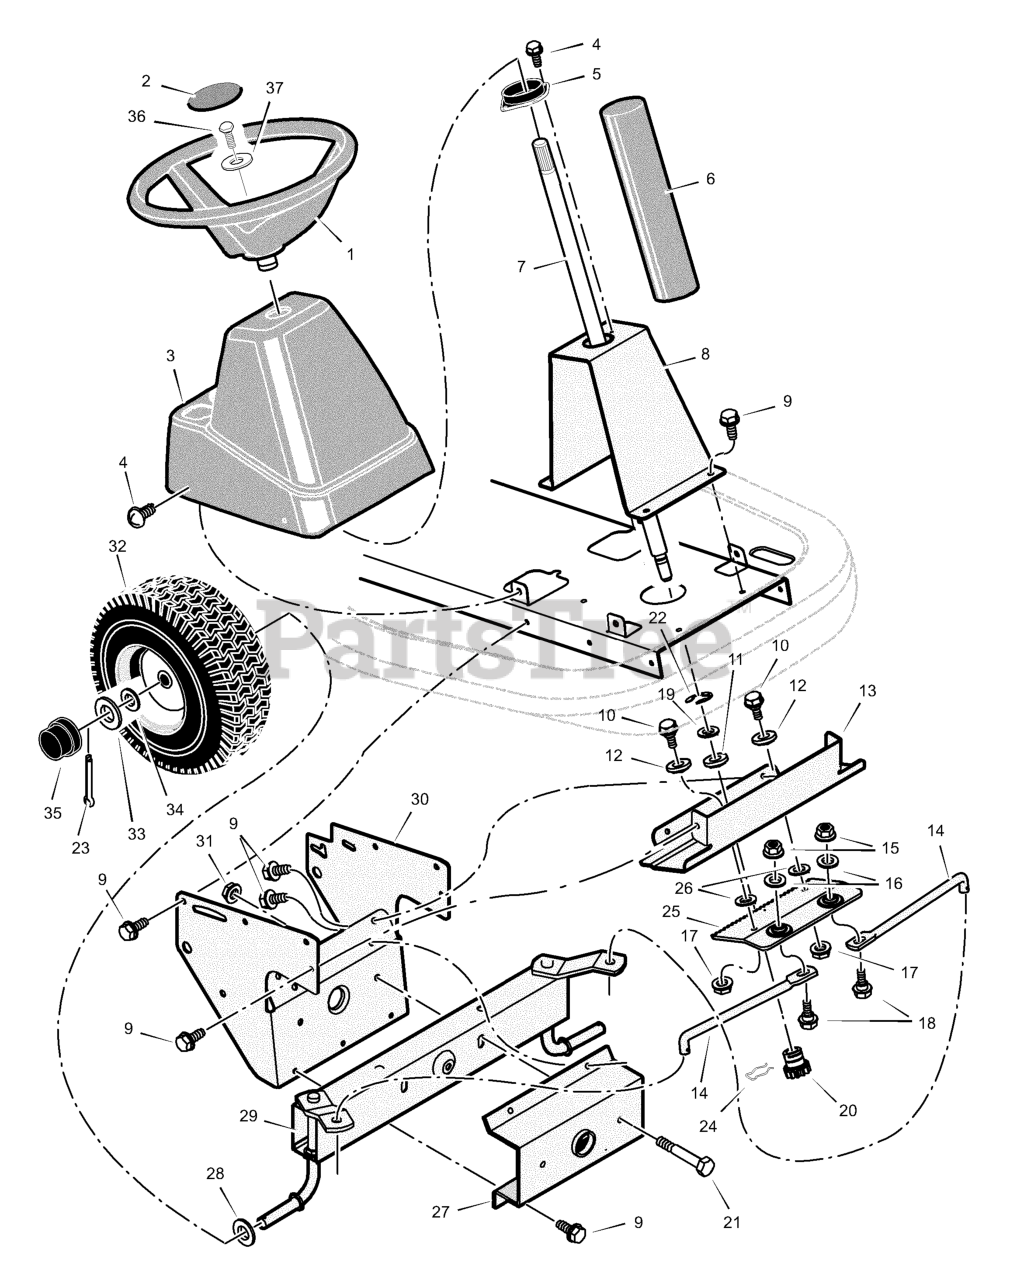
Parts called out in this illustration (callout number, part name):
1	Wheel, Steering
2	Insert, Steering (Black)
3	Console, Low (Gray)
4	Screw
5	Bearing, Upper Steering
6	Tube, Steering (Black)
7	Shaft, Steering
8	Support, Steering
10	Bolt, Shoulder
11	Bearing, Lower Steering
13	Plate, Gear Mounting
14	Link, Drag
15	Nut, Flange
16	Washer
17	Nut, Flange
18	Bolt, Hex
19	WASHER, 1-1.3 16G FLT
20	Gear, Pinion
21	Bolt, Hex
22	E-Ring, Retainer
23	Pin, Cotter
24	Retainer, Spring
25	Rack, Steering
26	Washer
27	Bracket, Axle Front
28	Washer
29	Axle & Spindle Assembly
30	Bracket, Support
31	Nut, Flange
32	Wheel, Front
34	Washer
35	Cap, Hub
36	Screw, Hex
37	Washer
